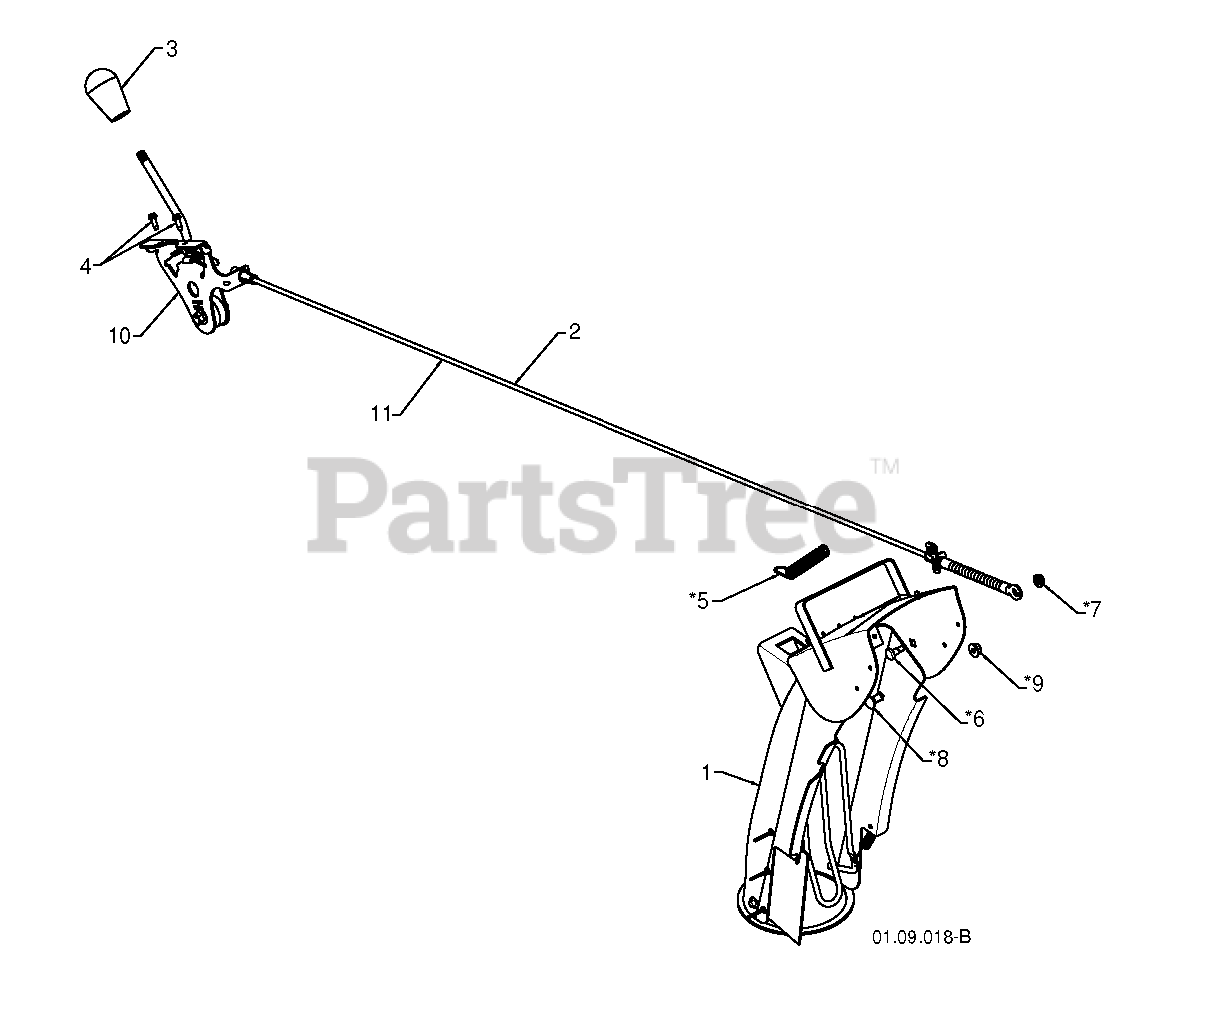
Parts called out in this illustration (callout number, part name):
2	CONTROL.ASM.DEFLECTOR
3	KNOB LEVER, BLACK
4	SCREW #10-24 X 5/8
5	SPRING.DEFLECTOR.REM.CHUTE
6	BOLT, SHOULDER
7	NUT.HEX.FLANGE.1/4
8	BOLT
9	NUT.LOCK.5/16-18
10	RP CNTRL.HEAD.ASSEM.DEFLECTOR
11	SERVICE.CHUTE.DEF.CBL.GRY
